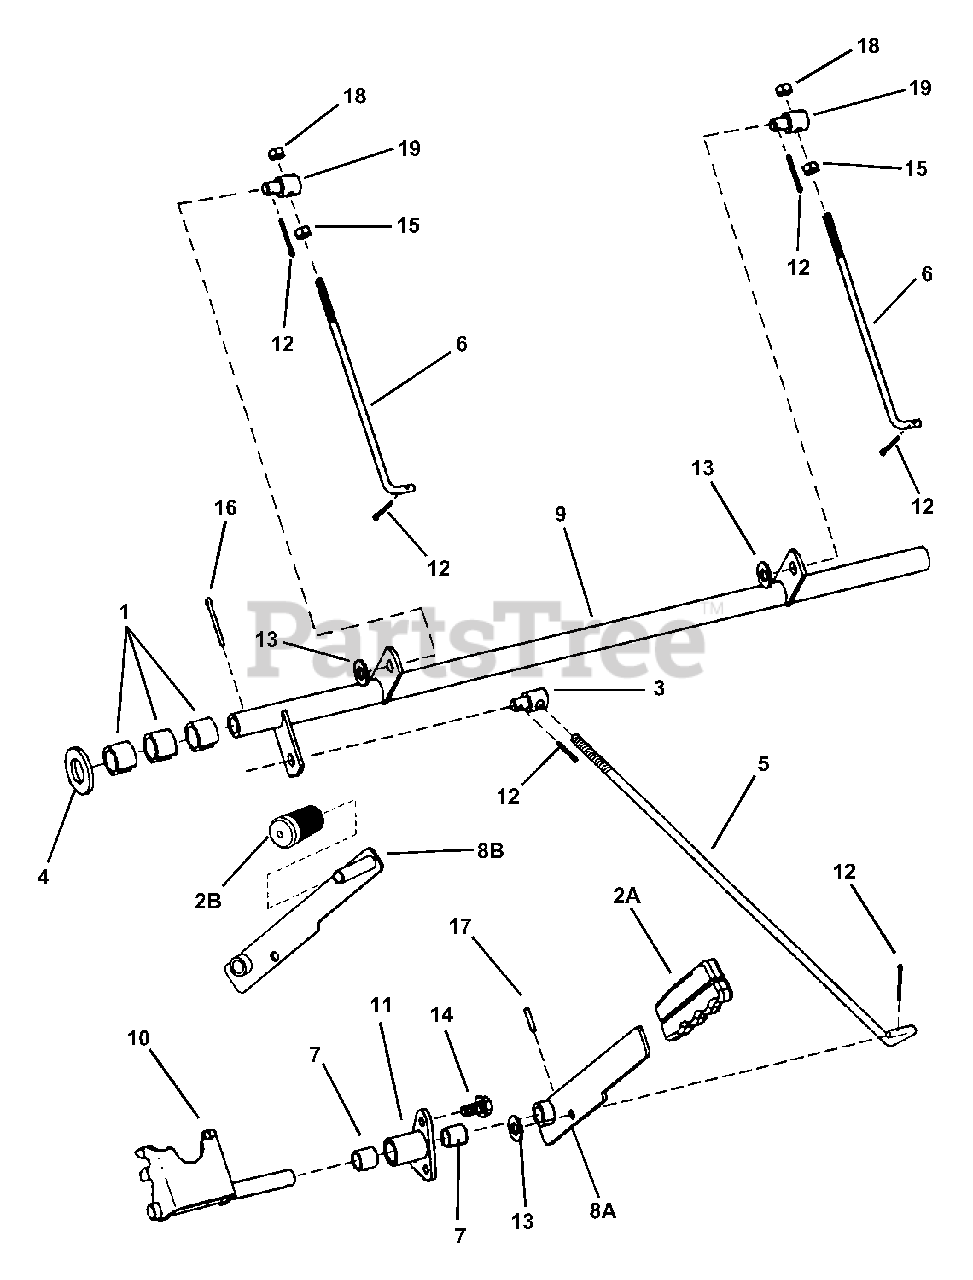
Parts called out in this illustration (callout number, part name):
1	RING, Rear Lift Arm
2A	GRIP, Flat Bar (Models ZM2200K & ZM2500K)
2B	GRIP, Park Brake Lever (Models ZMT2500KH, MZM2200KH, MZM2300K, ZM2501KH, ZM2502KH)
3	SWIVEL, Adjustable
4	WASHER, 3/4" I.D. x 1-1/8" O.D. x 1/16 Thick, Flat
5	ROD, Brake Parking
6	ROD, Hydrostatic Brake
7	SLEEVE Bearing, 1/2 I.D. x 5/8 O.D.
8A	WELDMENT, Brake Arm (Models ZM2200K & ZM2500K)
8B	WELDMENT, Brake Arm (Models ZMT2500KH, MZM2200KH, MZM2300KH, ZM2501KH, ZM2502KH)
9	SHAFT, Brake (Weldment)
10	BRACKET, Joystick Lockout (Weldment)
11	PLATE, Support (Weldment)
12	COTTER PIN, 3/32 x 3/4"
13	WASHER, 3/8" Flat
14	SCREW, 5/16-18 x 5/8" Hex Self-Tapping
15	HN, 1/4F GR5 YZ
16	COTTER PIN, 1/8 x 1-1/4
17	PIN, 1/8 x 3/4" Roll
18	NUT, 1/4-28 Hex Nyloc
19	SWIVEL, 1/4" Smooth
